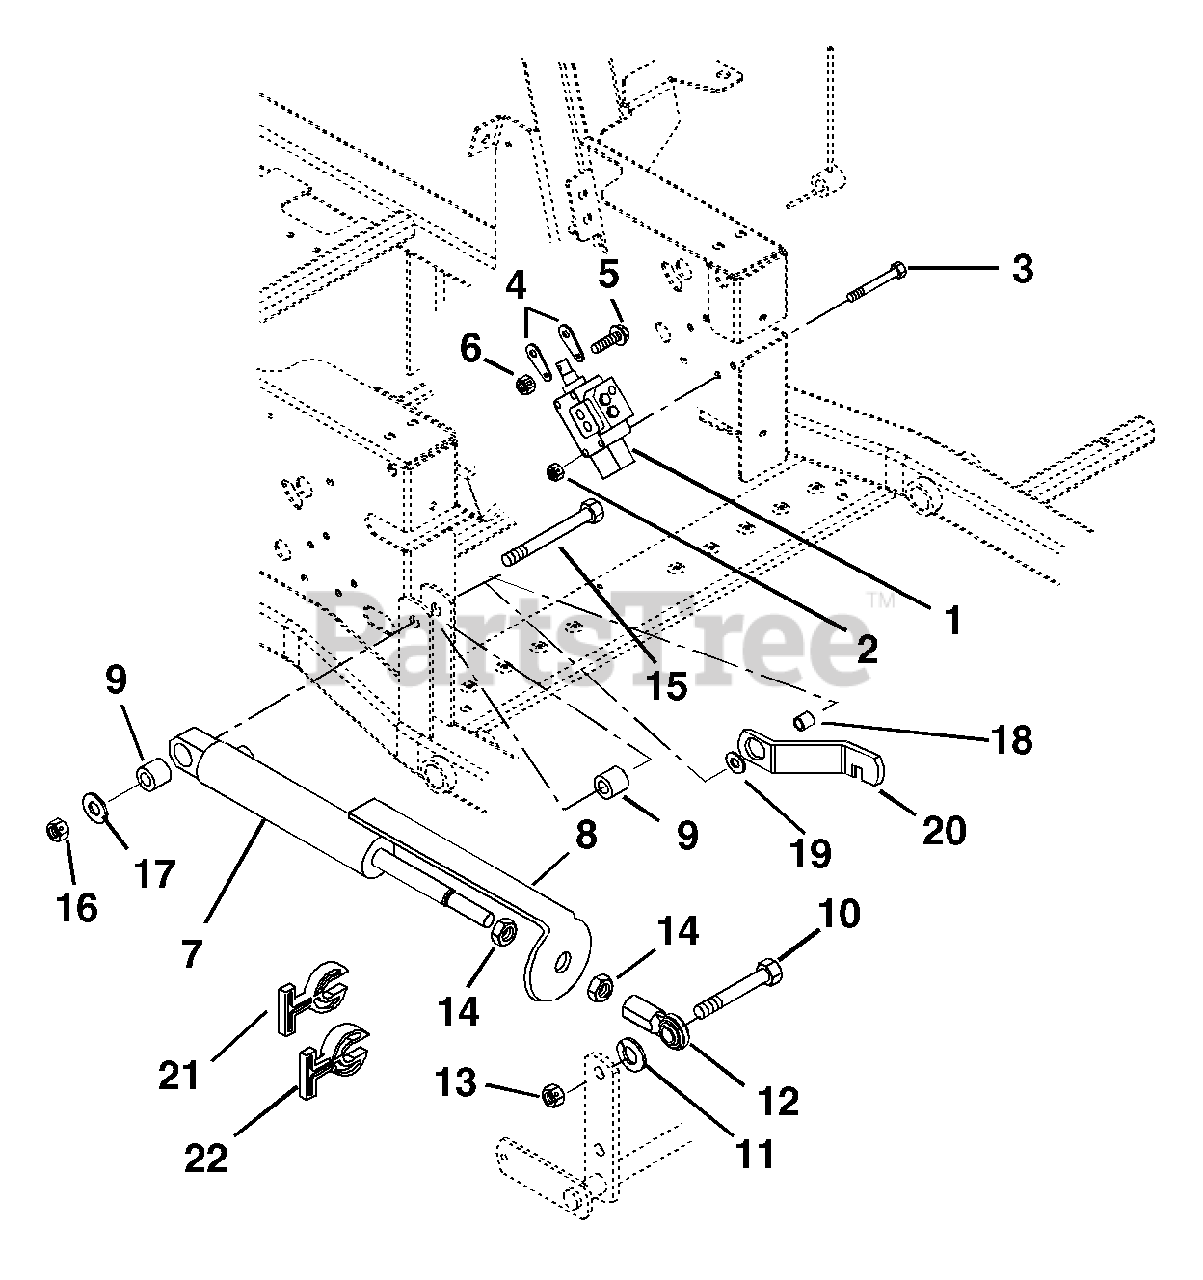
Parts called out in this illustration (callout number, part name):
1	Valve, Hydraulic Lift
2	Nut-Locking-Nylon .25 - 20
3	Bolt-Hex .25 - 20 x 2.75 Grade 5
5	Screw-Machine 10 - 24 x 1.00 Hex Washer Head
6	Nut-Locking-Nylon 10 - 24 with Insert
7	Cylinder-Hydraulic Lift
8	Strap-Height of Cut Indicator
9	Bushing .516 x 1.000 x 1.050
10	Bolt-Hex .62 - 11 x 2.25 Grade 8
11	Washer-Lock .62 x .156
12	Rod End-Right Hand-Female 5/8
13	Nut-Locking-Center .62 - 11
14	Nut-Jam .625 - 18
15	Bolt-Hex .50 - 13 x 3.75 Grade 5
16	Nut-Locking-Center .50 - 13
17	Washer-Flat-Steel .515 x 1.625 x .250
18	Bushing-Flange .515 x .750 x .275 x 1.120
19	Wave-Washer .76 x 1.12 x .08
21	Stop, Cylinder .34 Thick
22	Stop, Cylinder .68 Thick
